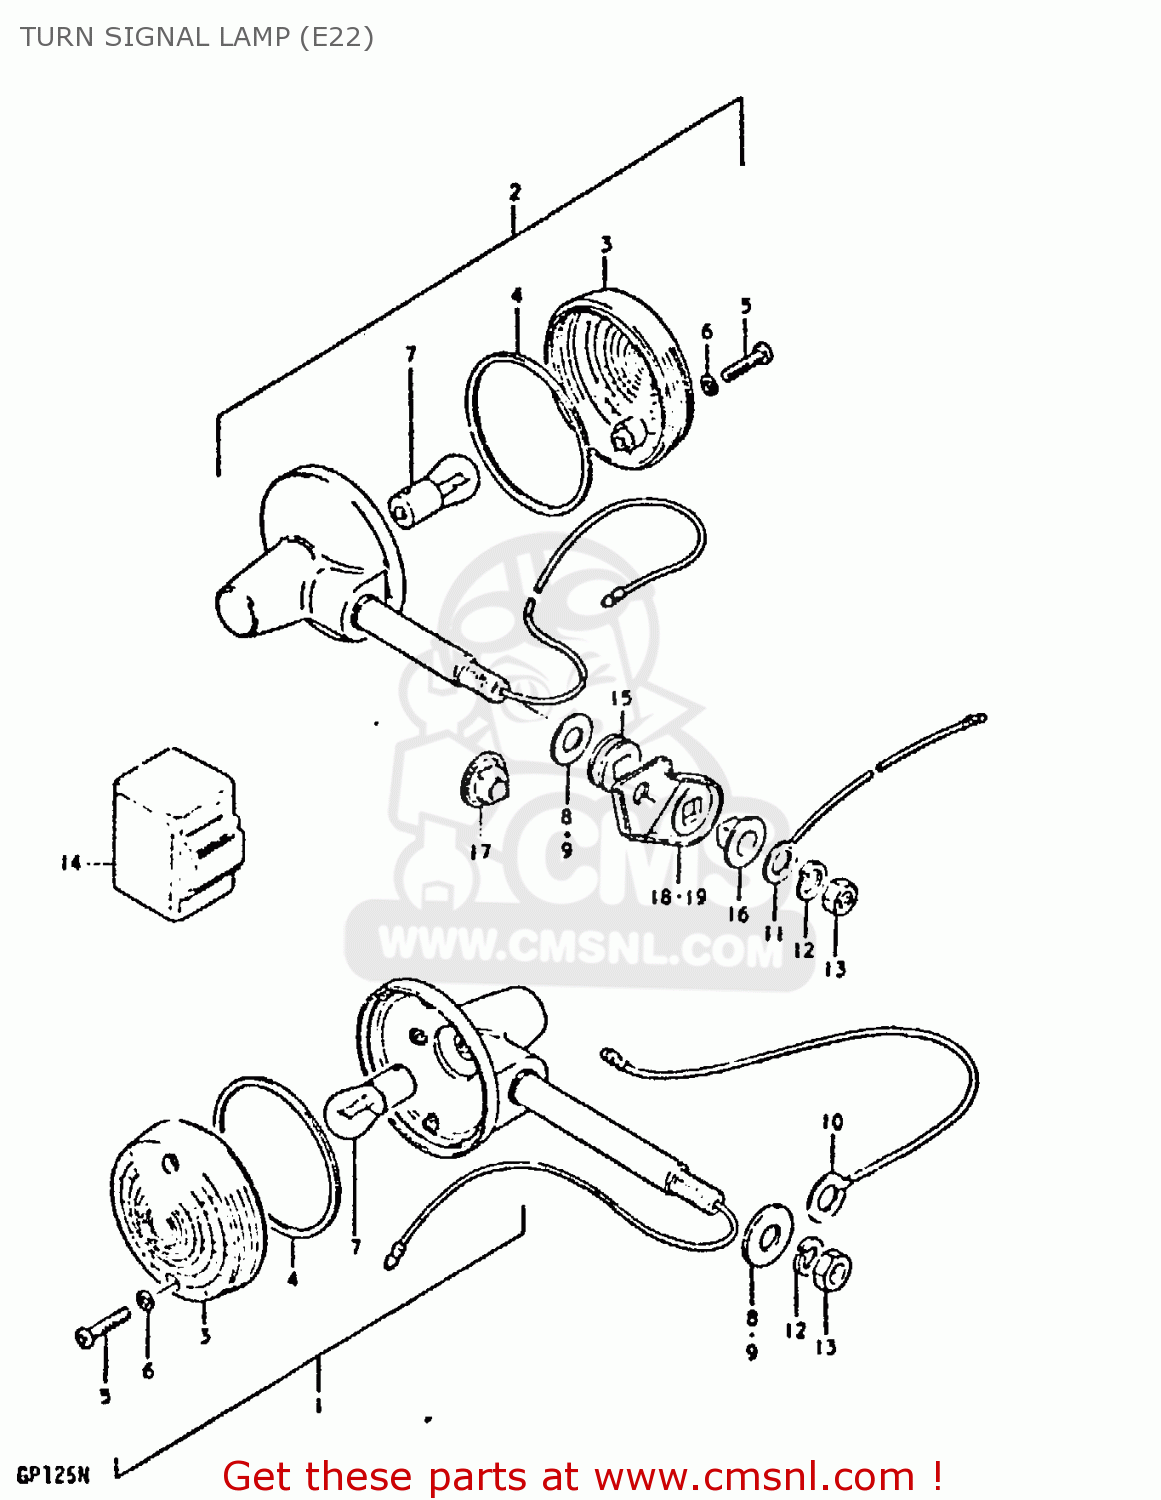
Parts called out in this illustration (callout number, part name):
1	LAMP, FRONT TURN SIGNAL
2	LAMP, REAR TURN SIGNAL
3	LENS
4	GASKET (NAS)
5	SCREW
6	GASKET (NAS)
7	BULB (6V,21W)
8	WASHER (10.5X30X2.3)
10	LEAD WIRE,EARTH
12	LOCK WASHER
13	NUT
14	RELAY, TURN SIGNAL
